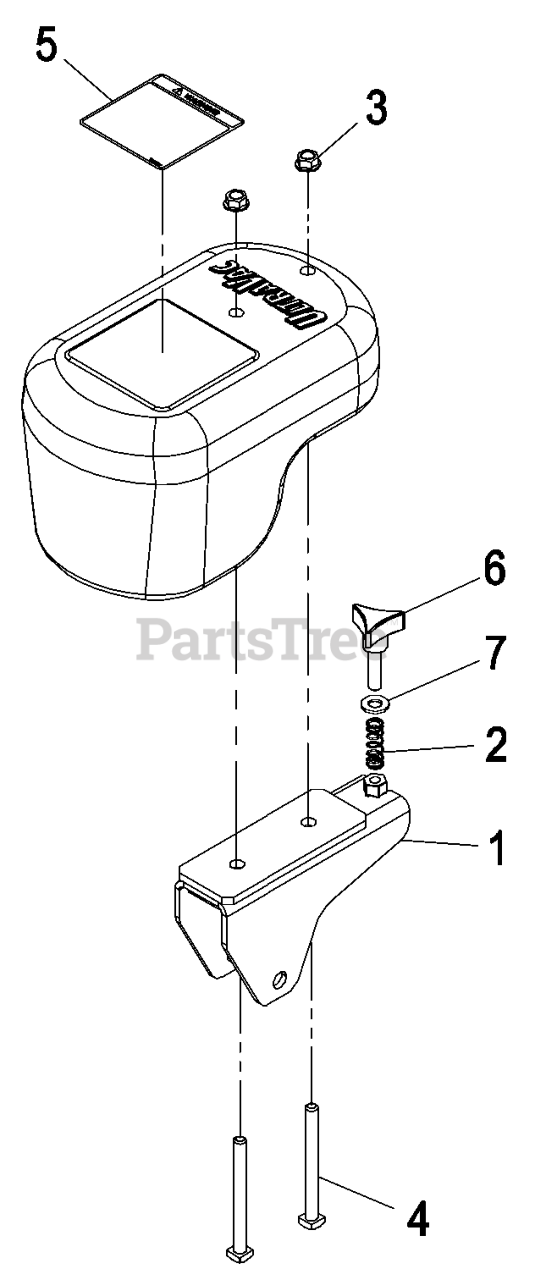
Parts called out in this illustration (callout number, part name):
1	ASM,CASTER WEIGHT BRACKET
3	NUT-HHF, WHIZ
4	BOLT, SQUARE HEAD YZ
5	DECAL,WEIGHT
7	WASHER-FLAT
